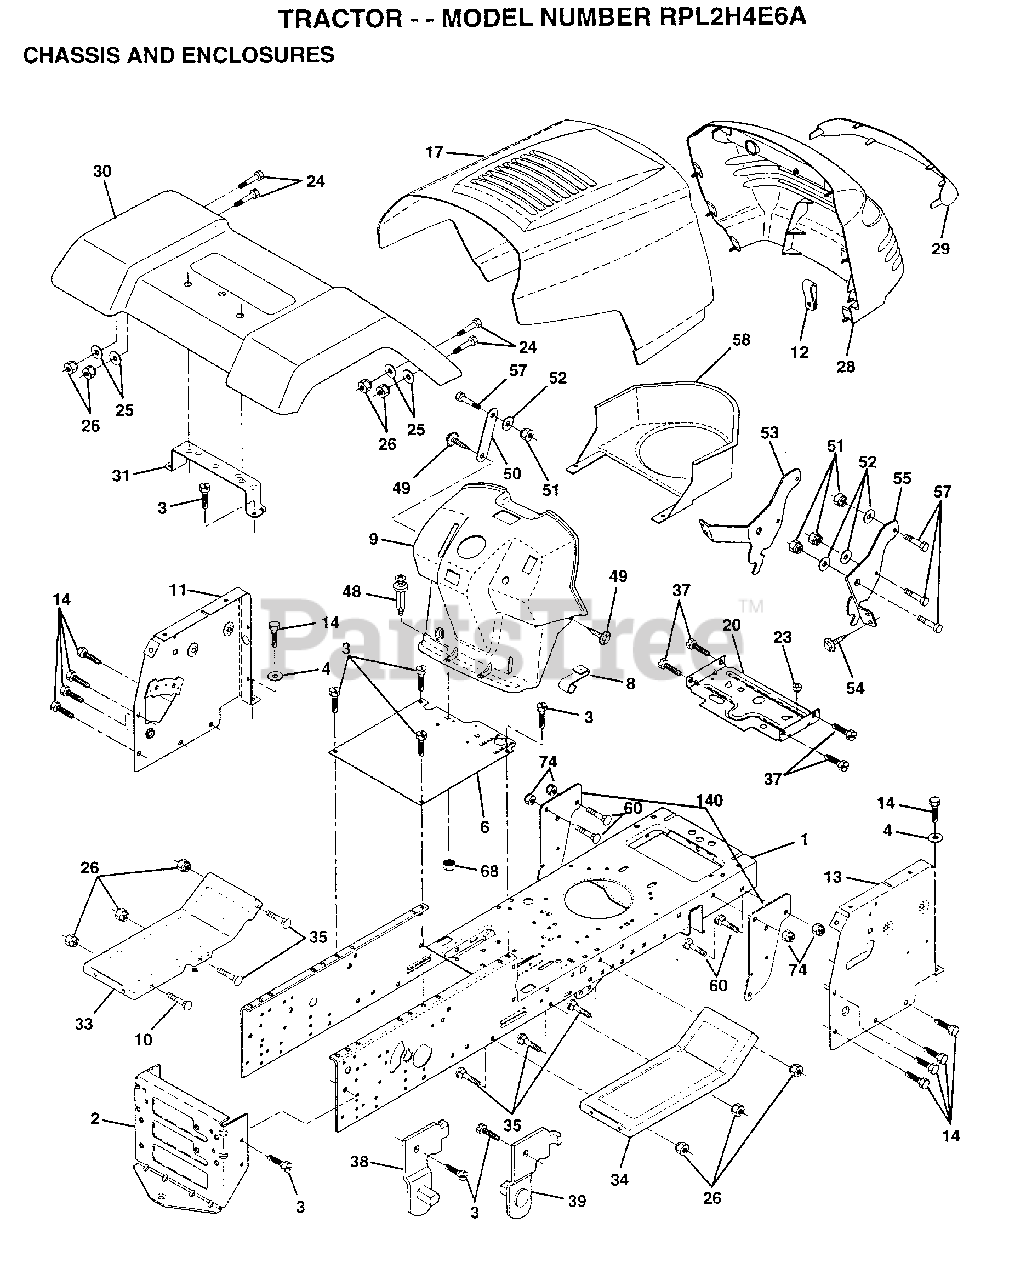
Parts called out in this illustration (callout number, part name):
1	CHASSIS WLDMT 11G
3	SCREW
4	WASHER
8	"CLIP,INSULATOR"
11	PANEL.DASH.LH.
12	CLIP.TINNERMAN
13	PANEL.DASH.RH
14	SCREW LT
20	PLATE.MTG.BTRY.TK
24	BOLT
25	WASHER
26	NUT
29	LENS GRILLE
31	BRKT FENDER
33	FOOTREST LH
34	FOOTREST RH
35	BOLT
37	SCREW LT
38	BRACKET ASM LH
39	BRACKET ASM RH
48	RIVET.PUSH.PLATE
49	SCREW HEX CRT
50	BRACE SUPT DASH
51	NUT
52	WASHER
53	BRACKET.GRILLE.LH
54	SCREW SPIDERLK #8 X 7/8
55	BRACKET.GRILLE.RH
58	AIR DUCT
60	BOLT
68	NUT
